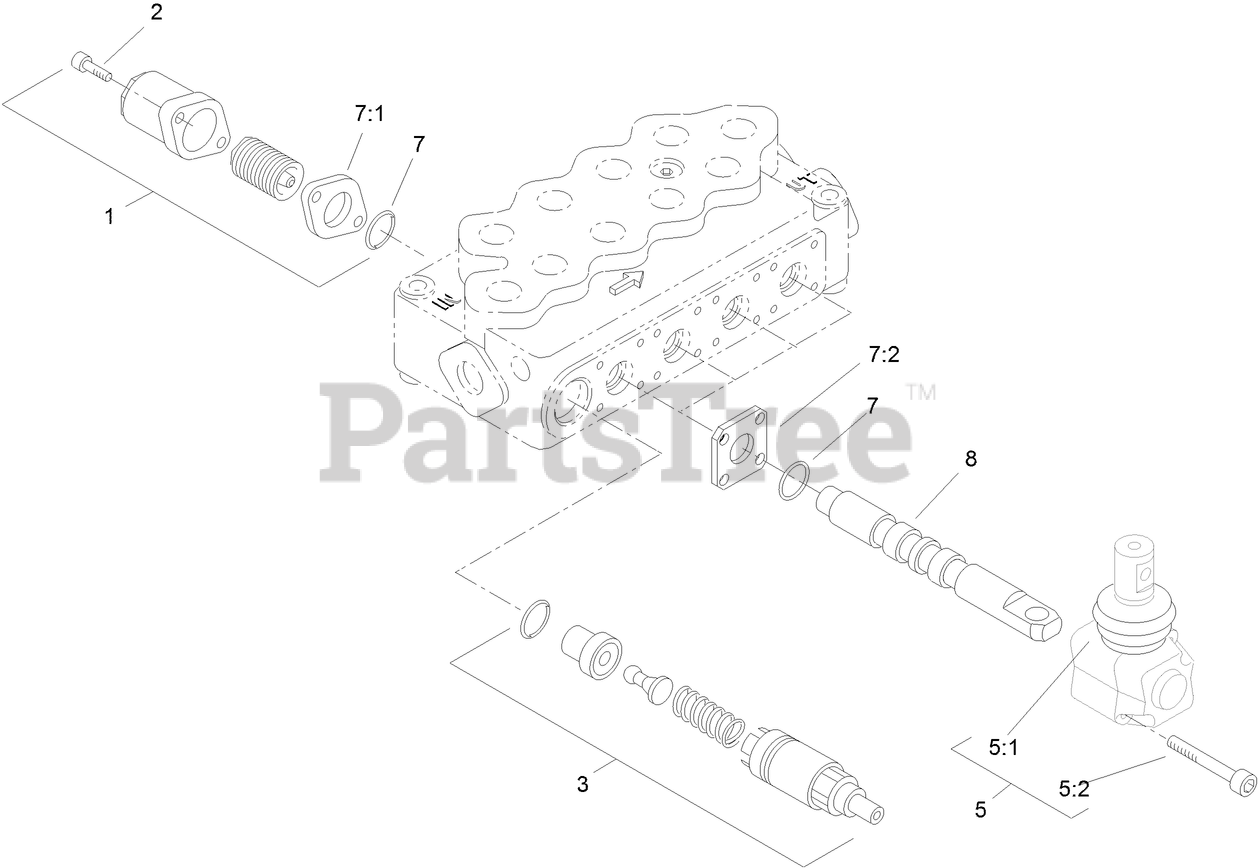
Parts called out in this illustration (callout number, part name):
1	HIGH FORCE SPRING KIT
1	STANDARD SPRING KIT
2	SCREW-CAP, END
3	VALVE-RELIEF
5	OPERATOR ASM
7	SEAL KIT
7:1	GASKET
7:2	GASKET
8	SPOOL-VALVE
